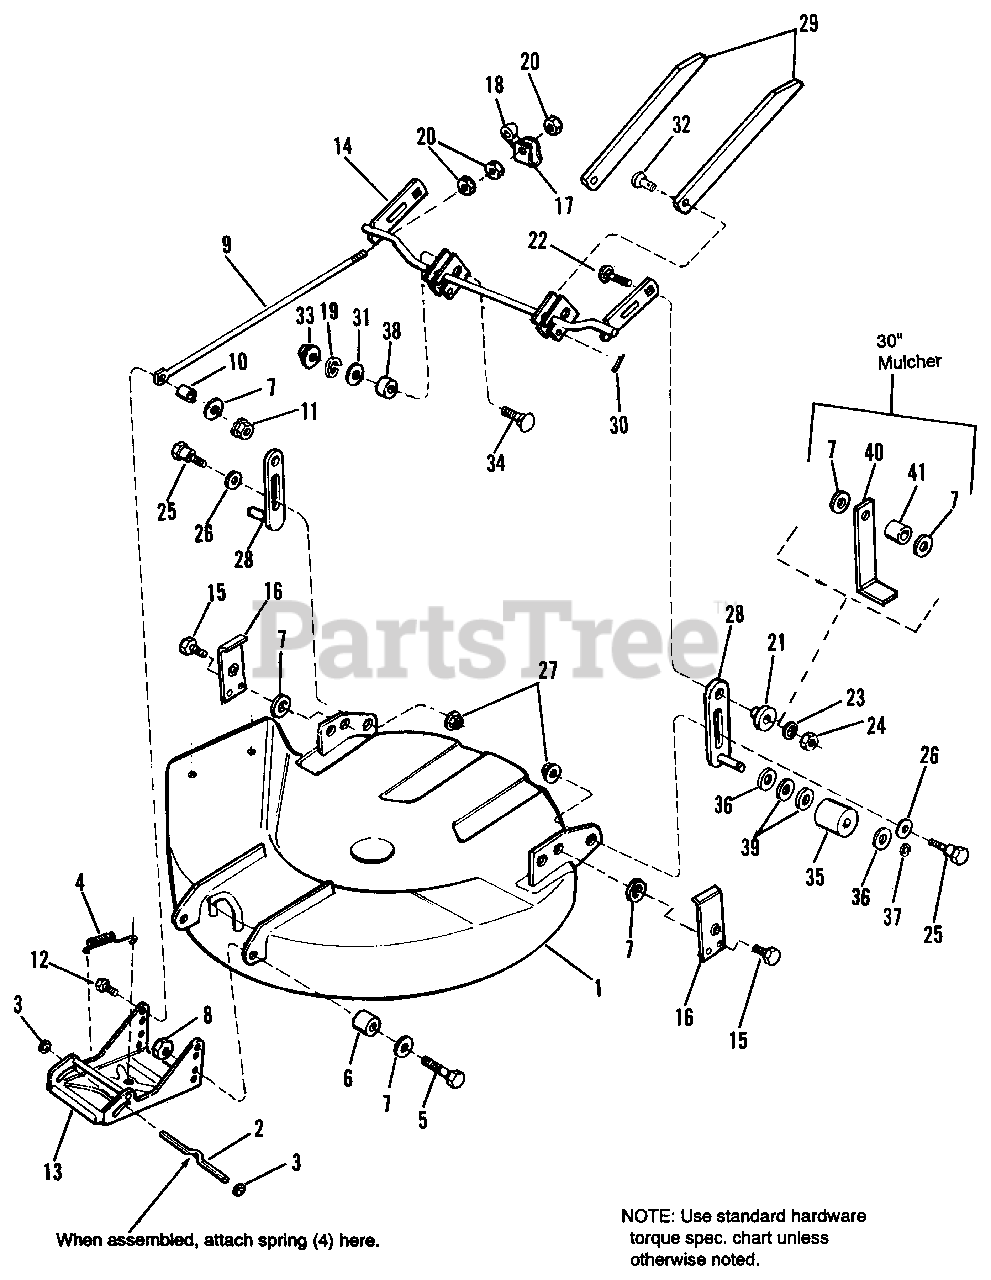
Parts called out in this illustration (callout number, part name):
1	HOUSING ASSY., 30" Std. (Orange)
1	HOUSING ASSY., 30" Mulcher (Orange)
3	PUSHNUT
5	CAPSCREW, Hex, 3/8-16 x 1-1/4
7	WASHER, Flat, 3/8 (Qty. 10, 30" Mulcher)
8	LOCKNUT, Hex, 3/8-16
9	ROD, Adjustment
11	NUT, Hex, Flange Lock, 3/8
12	CAPSCREW, Hex Hd., 3/8-16 x 1
13	HITCH ASSY.
14	ARM ASSY., Mower
15	SCREW, Taptite 5/16-18 x 3/4
16	PLATE, Pivot Support
18	SPACER
19	LOCKWASHER, 5/16
20	JAMNUT, Hex, 1/2-13
21	NUT, Hex Adjusting, .99 DIA .687
22	CARRIAGE BOLT, 3/8-16 x 1-1/2 (30" Std.)
22	CARRIAGE BOLT, 3/8-16 x 2 (30" Mulcher)
23	LOCKWASHER
24	NUT, Hex, 3/8-16
25	BOLT, Shoulder, 3/8-16 X 1.34
26	WASHER, Flat
27	NUT, Hex, Flange, Whizlock, 3/8-16
28	SUPPORT ASSY., Roller
29	BAR, Mower Transport
30	PIN, Retaining
31	WASHER, Flat, 5/16
32	PIN, Locking
33	NUT, Hex, 5/16-18
34	CARRIAGE BOLT, 5/15-18 x 1-1/4
36	WASHER, 21/32 x 1-1/8 x 1/16
37	RING, Retaining
39	WASHER, 5/8
40	BRACKET, Roller (30" Mulcher)
41	SPACER (30" Mulcher)
